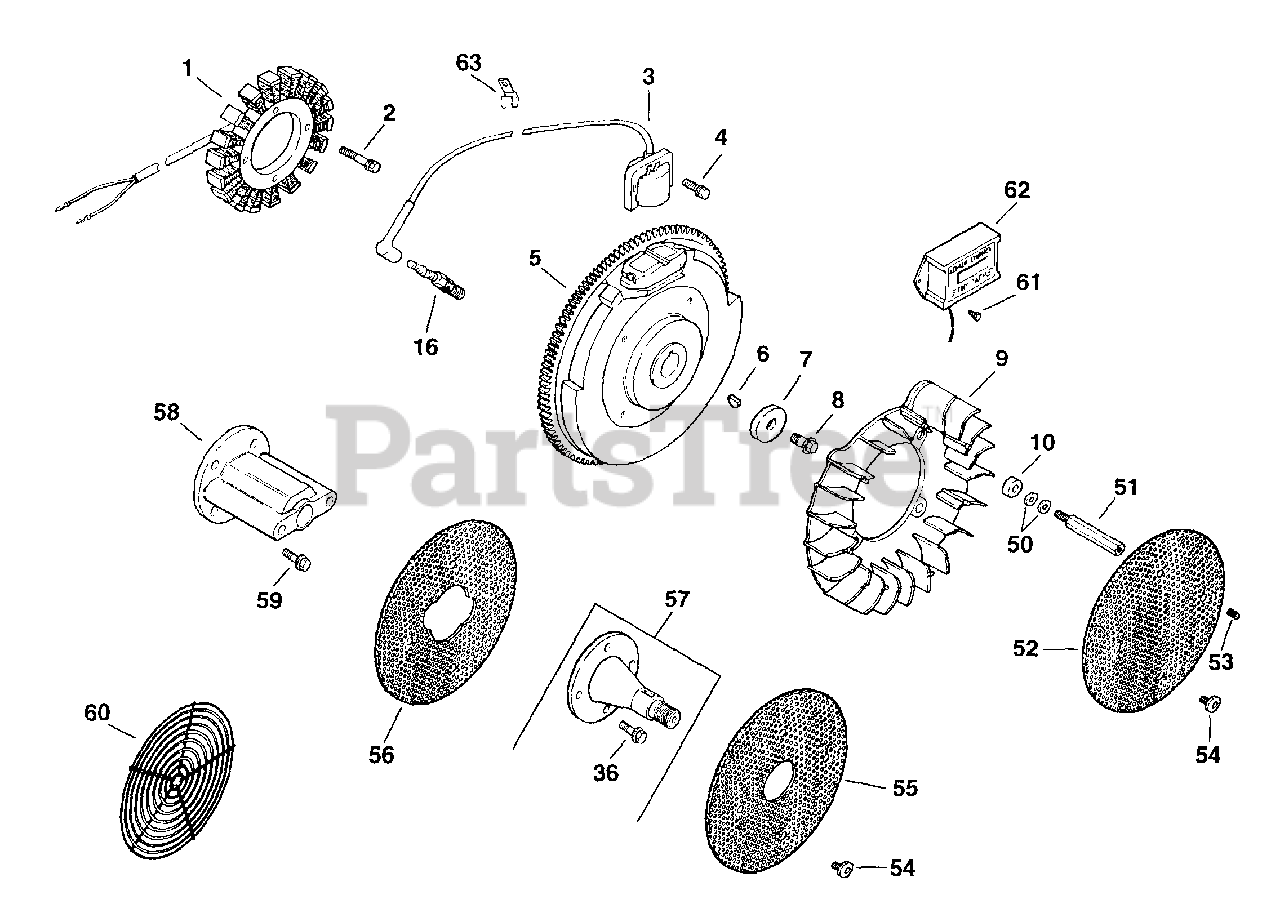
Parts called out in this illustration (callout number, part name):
1	KIT - USE 54 755 09
2	SCREW - USE M-548025
3	MODULE, IGNITION-USE 24 584 45-S
4	Screw, hex. flange M5x0.8x20
6	KEY, 3/16" X 5/8"
7	WASHER, FLAT 13/32"
8	SCREW, FLG M10X1.5X45 - (#25086361S)
9	FAN (KM)-USE 24 157 15-S
10	BOLT - USE 25 086 47
16	PLUG, SPARK (STD)
50	WASHER, FLAT 1/4" (O.D. 5/8")
51	KIT - USE 24 755 79
52	SCREEN - USE 24 162 20
53	SCREW, SKT SET #10-24X1/4"
54	SCREW - USE M-657010
2451804	LEAD - USE 25 518 34
2451806-S	LEAD - DISCONTINUED
